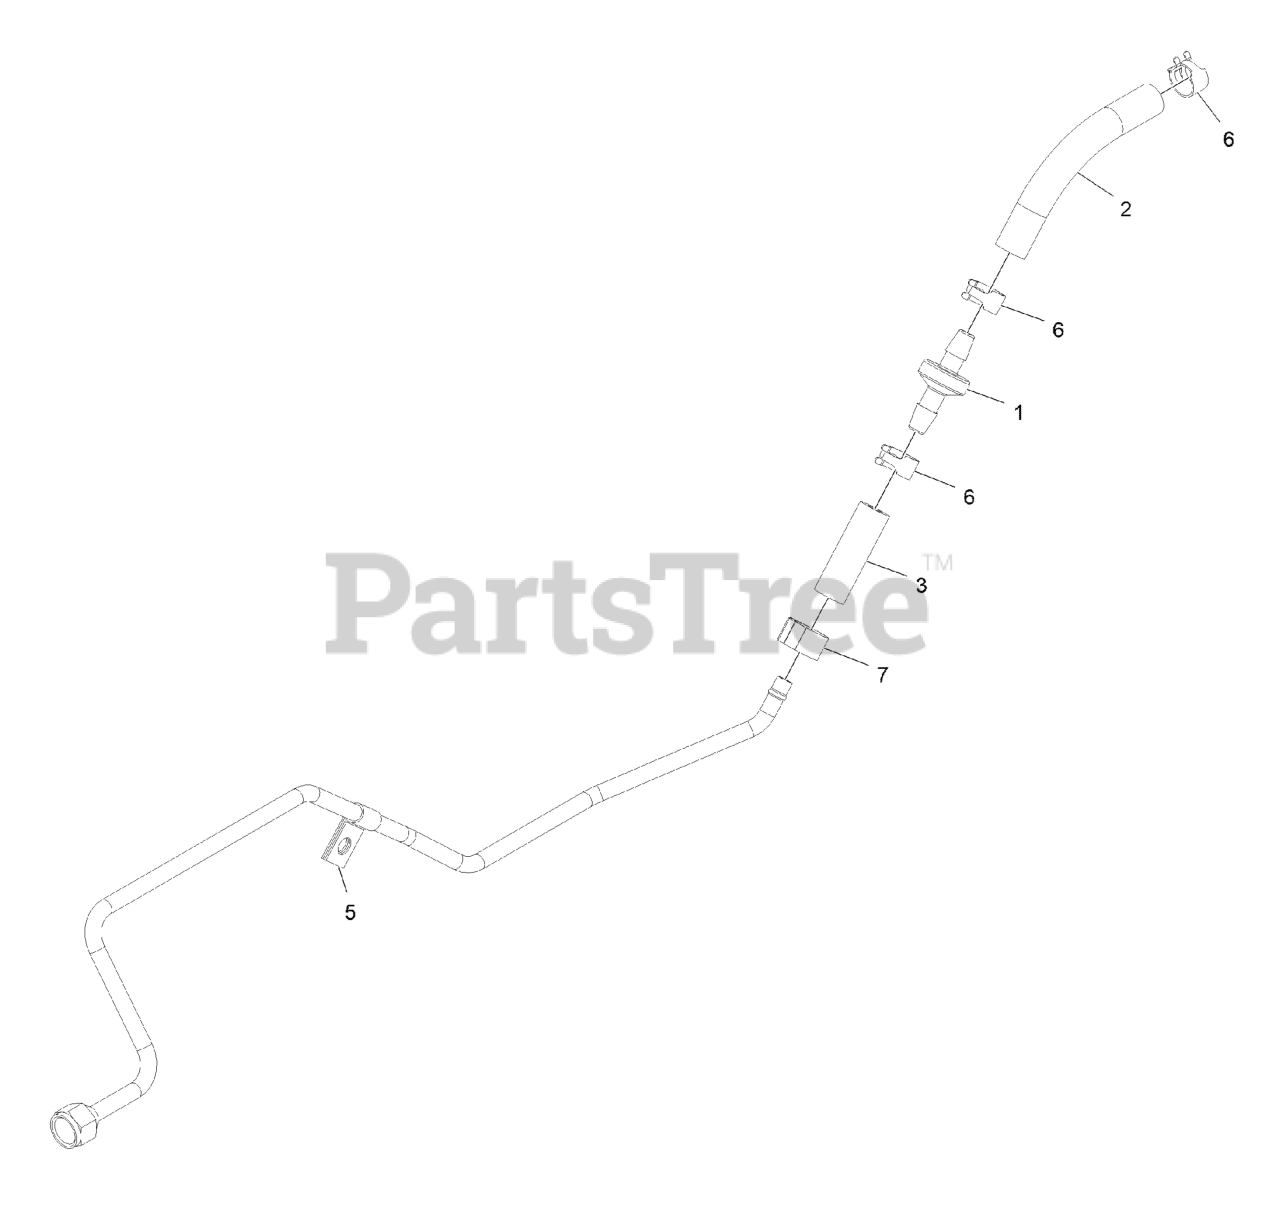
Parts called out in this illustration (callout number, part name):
1	VALVE-CHECK, FUEL
2	HOSE-FUEL
3	Hose-Fuel
5	CLIP-CLOSED, INSULATED
6	CLAMP-HOSE
7	Clamp-Hose, Fuel
